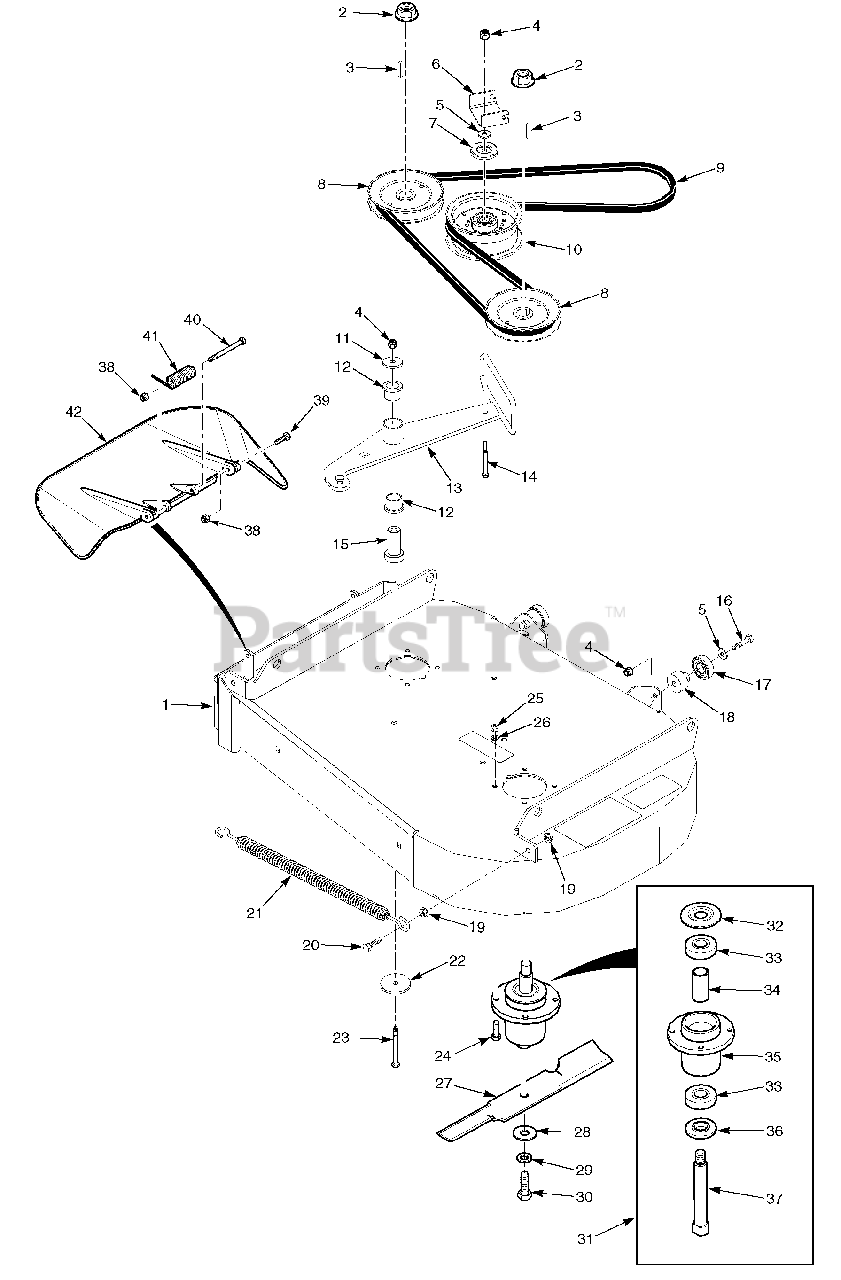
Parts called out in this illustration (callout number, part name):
1	Cutter Deck Weldment w/Decals
2	Nut, 3/4-16 Spiral Lock
3	Key, 1/4 x 1/4 x 1-1/4"
4	Nut, Elastic Stop 3/8-16
5	Flatwasher, 3/8-.391 x .938 x .105 HD
6	Bracket, Belt Guide
7	Dust Shield
8	Pulley, 5.73" Dia.
9	Belt, Deck Drive
10	Pulley, 5" Idler
11	Flatwasher, 3/8-.406 x 1-1/2"
12	Bearing
13	Idler Arm Assembly
14	Bolt, Hex Head 3/8-16 x 3-1/4"
15	Pivot, Idler
16	Bolt, Hex Head 3/8-16 x 2-1/4"
17	Bearing
18	Spacer, Bearing
19	Nut, Serrated Flange 3/8-16
20	Bolt, Hex Head 3/8-16 x 1-1/2" Gr.8
21	Spring, Deck Idler
22	Flatwasher, 3/8-.406 x 2-1/4 x .187
23	Bolt, Hex Head 3/8-16 x 3-3/4"
24	Bolt, Hex Head 5/16-18 x 1-1/2" Gr.8
25	Nut, Elastic Stop 5/16-18
26	Lockwasher, 5/16" Spring
27	Cutter Blade, 18"
28	Flatwasher, 5/8-.688 x 1-3/4 x .134 HD
29	Lockwasher, 1/2" Spring
30	Bolt, Hex Head 5/8-11 x 1-1/2"
31	Spindle Assembly
32	Debris Shield
33	Bearing
34	Spacer, Bearing
35	Spindle Housing Assembly
36	Protector, Bearing
37	Shaft, Spindle
38	Nut, Elastic Stop 5/16-18
39	Bolt, Hex Head 5/16-18 x 1-3/4"
40	Bolt, Hex Head 5/16-18 x 4-3/4"
41	Spring, Discharge Chute
42	Discharge Chute Assembly
